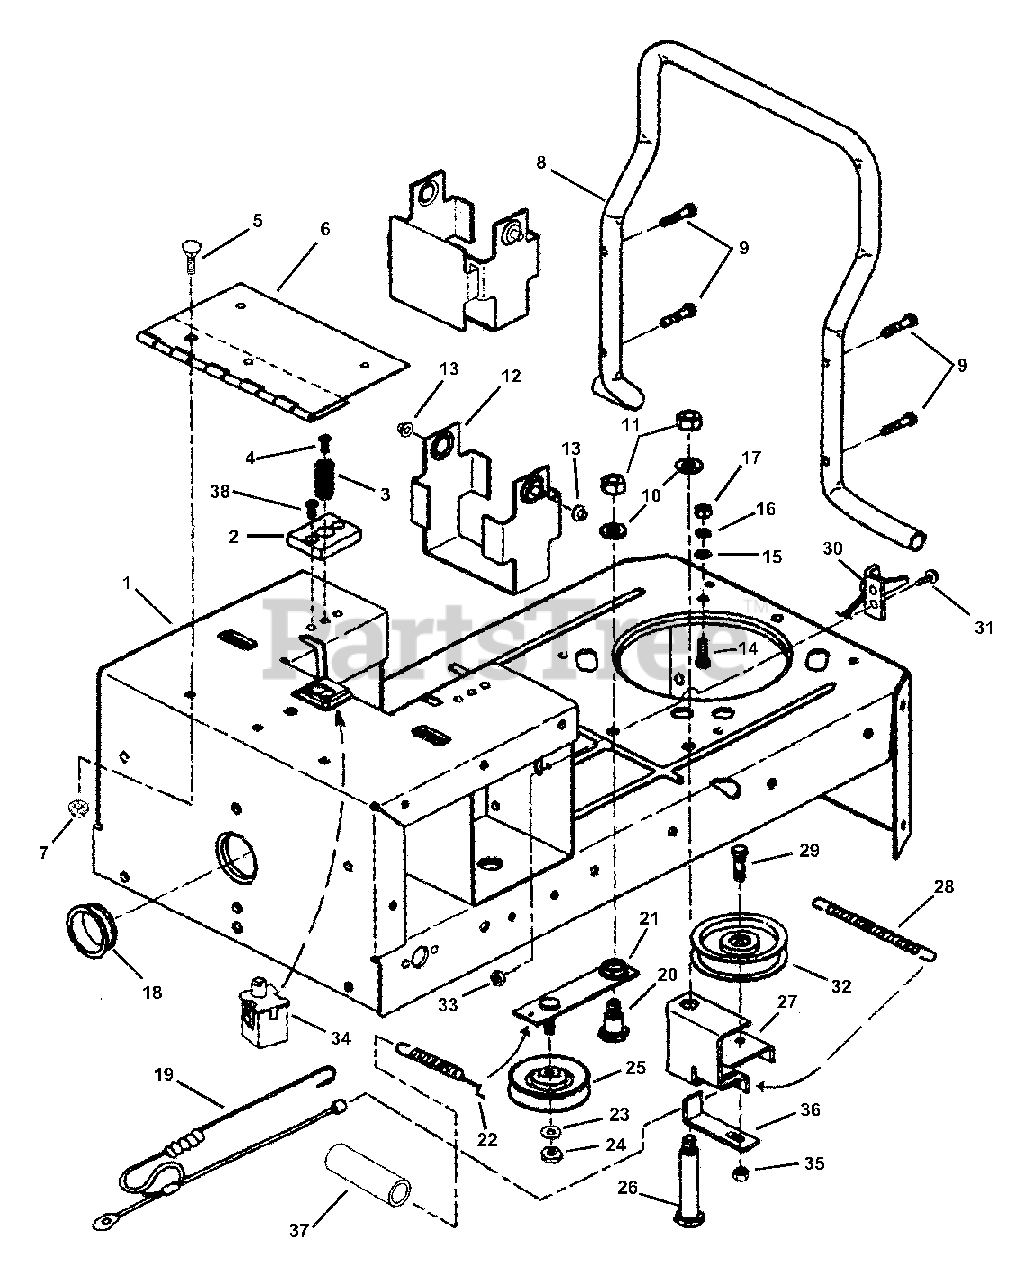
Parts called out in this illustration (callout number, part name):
1	FRAME, Rear
2	CUSHION, Seat Support
3	SPRING, Seat Support
4	SCREW, 1/4-20 x 5/8" Pan Head, Self-Tapping
5	BOLT, 5/16-18 x 1/2" Carriage, Grade 5
6	HINGE, Seat
7	NUT, 5/16-18 Hex Flange Lock, Grade 5
8	BUMPER, Rear
9	SCREW, 5/16-18 x 1-1/2" Self-Tapping
10	WASHER, 1/2" Flat
11	NUT, 1/2-13 Hex, Grade B
12	BRACKET, Battery
13	BUSHING
14	SCREW, 5/16-24 x 1" Hex Head Cap
15	RETAINER, 5/16 Bolt
16	WASHER, 5/16 Split Lock
17	NUT, 5/16-24 Hex, Grade 5
18	GROMMET
19	CABLE, Brake/Clutch
20	BOLT, 1/2-13 x 5/8" Thread, .75 x .788 Shoulder
21	WELDMENT, Primary Idler Arm
22	SPRING, Extension
23	WASHER, 3/8" Flat
24	NUT, 3/8-16 Hex Center Lock, Grade 5
25	PULLEY, Idler 3.50
26	BOLT, 1/2-13 x 5/8" Thread, .75 x 3.23 Shoulder
27	BRACKET, Hydraulic Idler
28	SPRING, 3/4" Extension
29	SCREW, 3/8-16 x 1-3/4" Hex Head Cap, Grade 5
30	CABLE, Hydro Release Valve
31	SCREW, #10-32 x 5/8" Hex Washer Head, Machine
32	IDLER, 4.12 Flat
33	NUT, #10-32 Hex Nyloc
34	SWITCH, Seat
35	NUT, 3/8-16 Hex Center Lock, Grade B or 5
36	GUIDE, Belt
37	COVER, Spring
38	FASTENER, Ratchet
